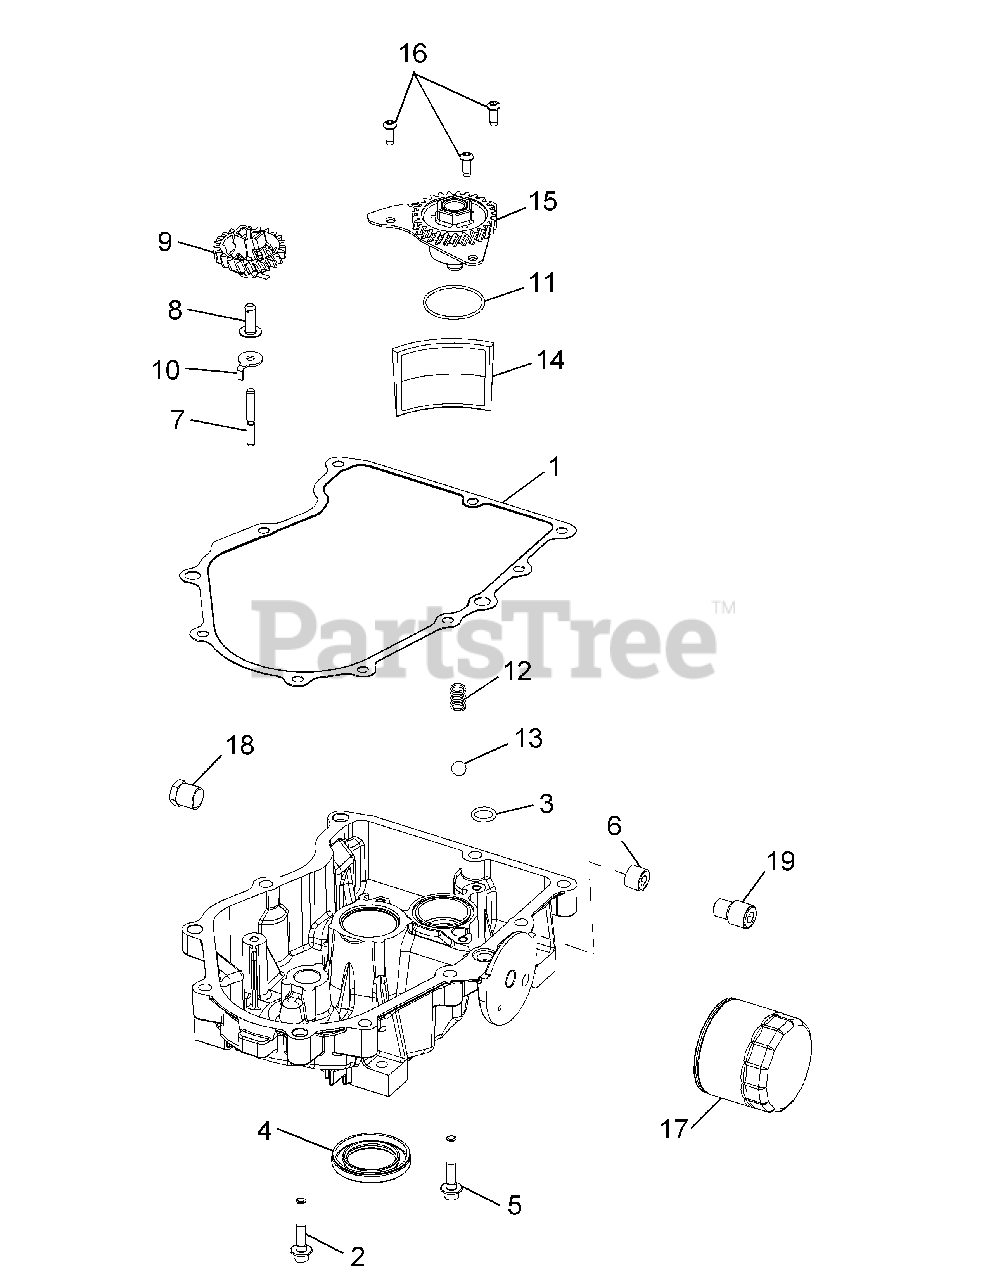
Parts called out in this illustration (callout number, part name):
1	Oil Pan Gasket
2	Flange Screw, M8 x 1.25 x .45
6	Pipe Plug, 3/8
7	Governor Gear Shaft
8	Governor Regulating Pin
9	Governor Gear Kit w/Pin
11	O-Ring (1.78" Dia.)
12	Compression Spring
13	Pressure Relief Ball
15	Oil Pump Assembly
16	Button Head Screw
18	Pipe Plug, 3/8
19	Oil Filter Nipple
